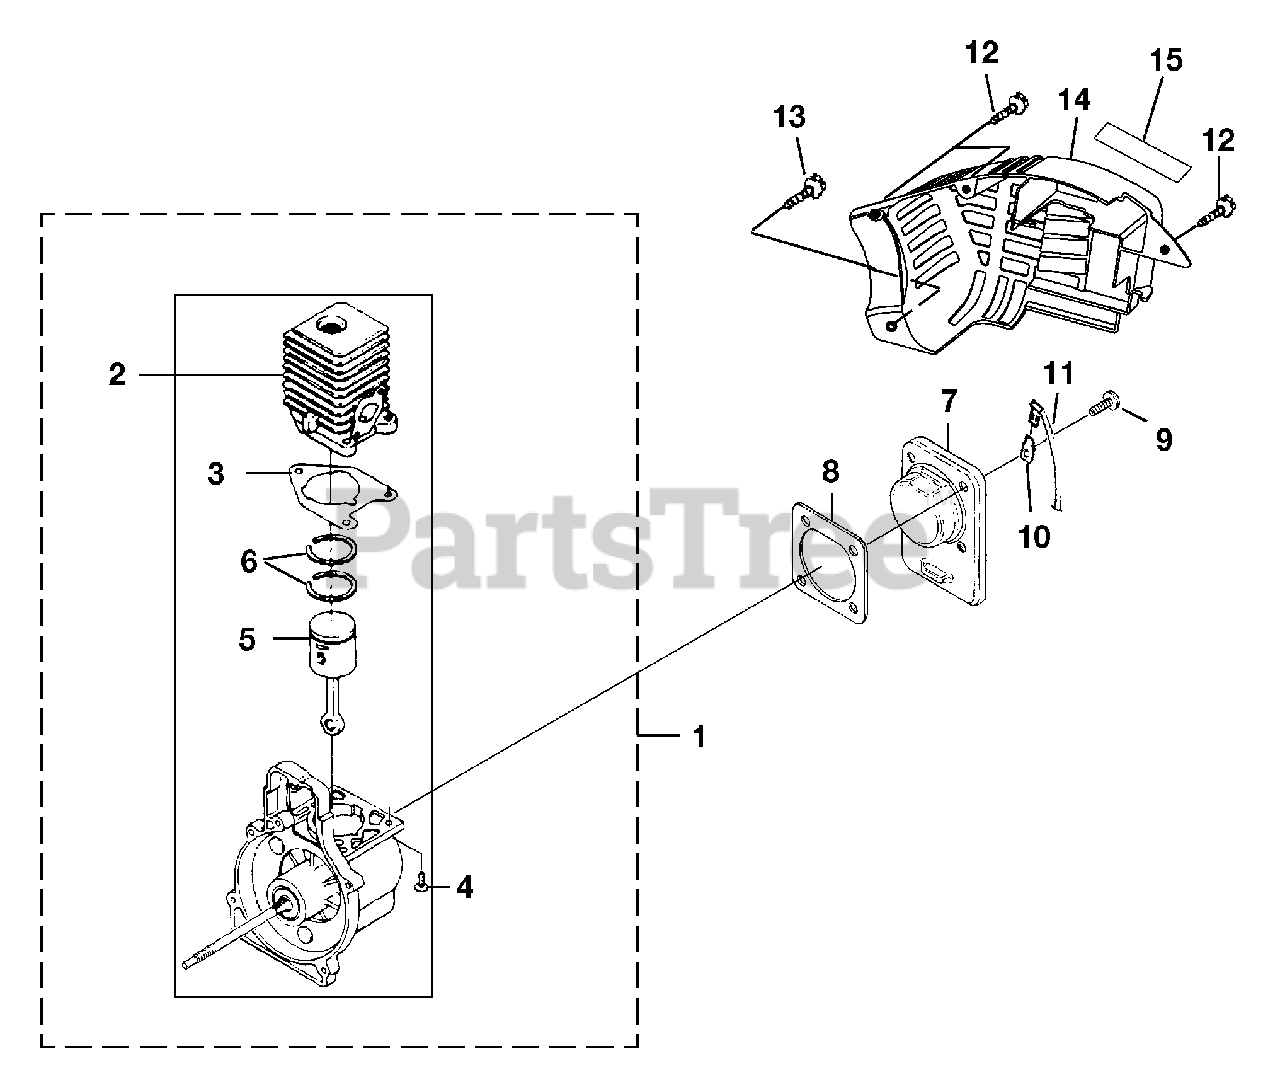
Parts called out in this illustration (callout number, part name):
1	SHORT BLOCK (30cc)
2	30cc CYLINDER
3	CYLINDER GASKET
4	SCREW (12-24 x 3/4 in. TOR x PAN HD.)
5	30cc PISTON ASSEMBLY
6	PISTON RING
7	CRANKCASE COVER
8	CRANKCASE GASKET
9	SCREW (10-24 x 9/16 in. PAN HD .)
10	MALE TAB
11	LEAD-GROUND TO HANDLE
12	SCREW (#8 x 1/2 in. PAN HD.)
13	PURCHASE LOCALLY
15	ZIP START DECAL
